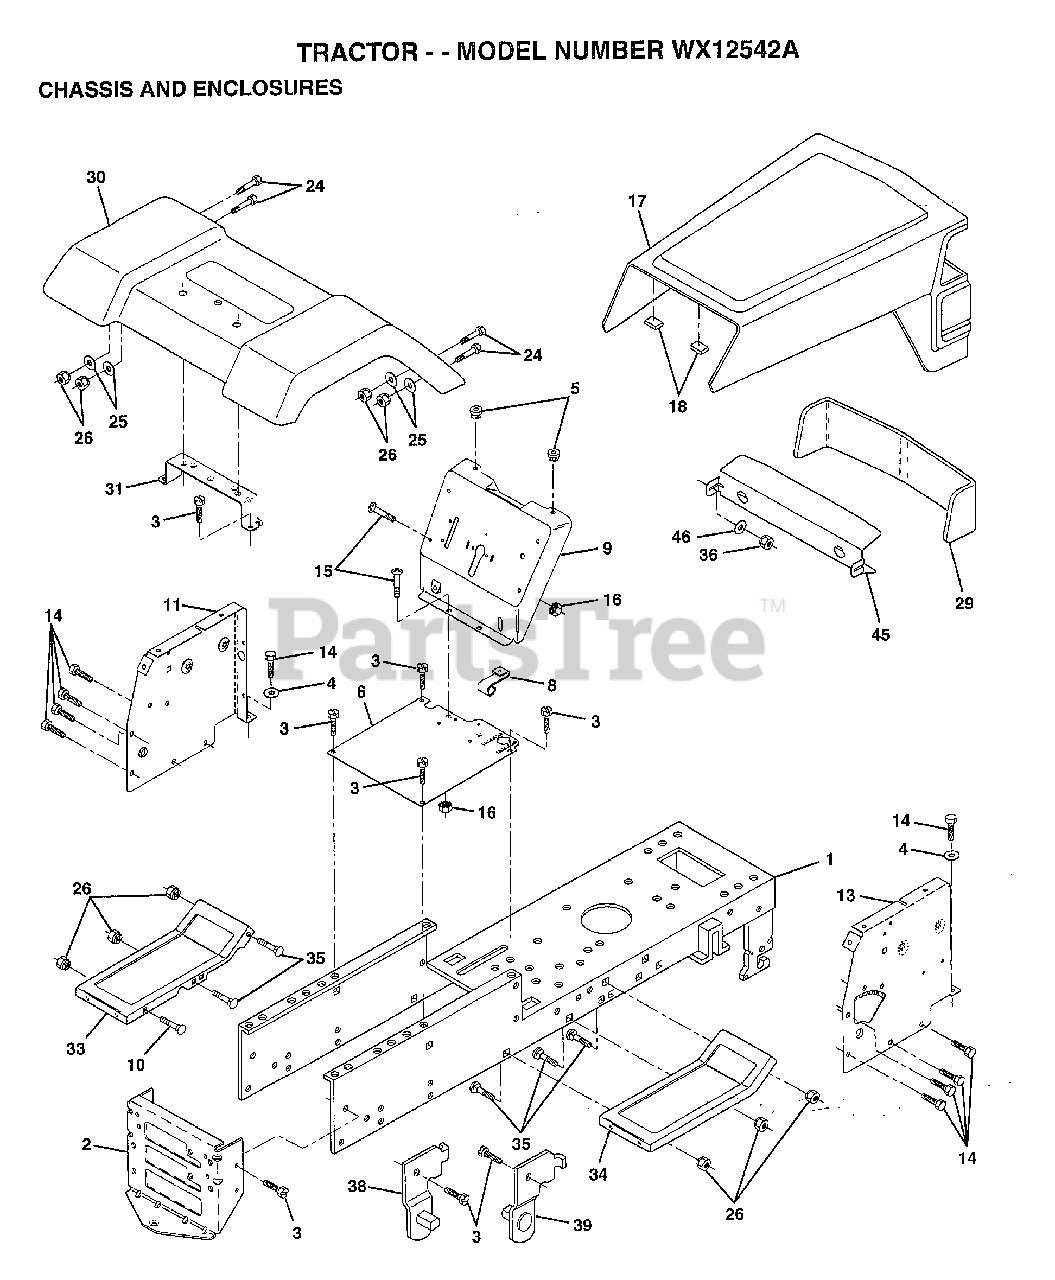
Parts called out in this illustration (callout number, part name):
1	CHASSIS.WLD.11GA
3	SCREW
4	WASHER
8	"CLIP,INSULATOR"
9	DASH.SLKSC.LT.1PC
11	DASH PANEL LH
14	SCREW LT
15	SCREW
17	HOOD/GRILLE.ASM.
24	BOLT
25	WASHER
26	NUT
31	BRKT FENDER
33	FOOTREST.LH.LT/GT
34	FOOTREST.RH.LT/GT
35	BOLT
36	PAL NUT LT
38	BRACKET ASM LH
39	BRACKET ASM RH
46	RETAINER
